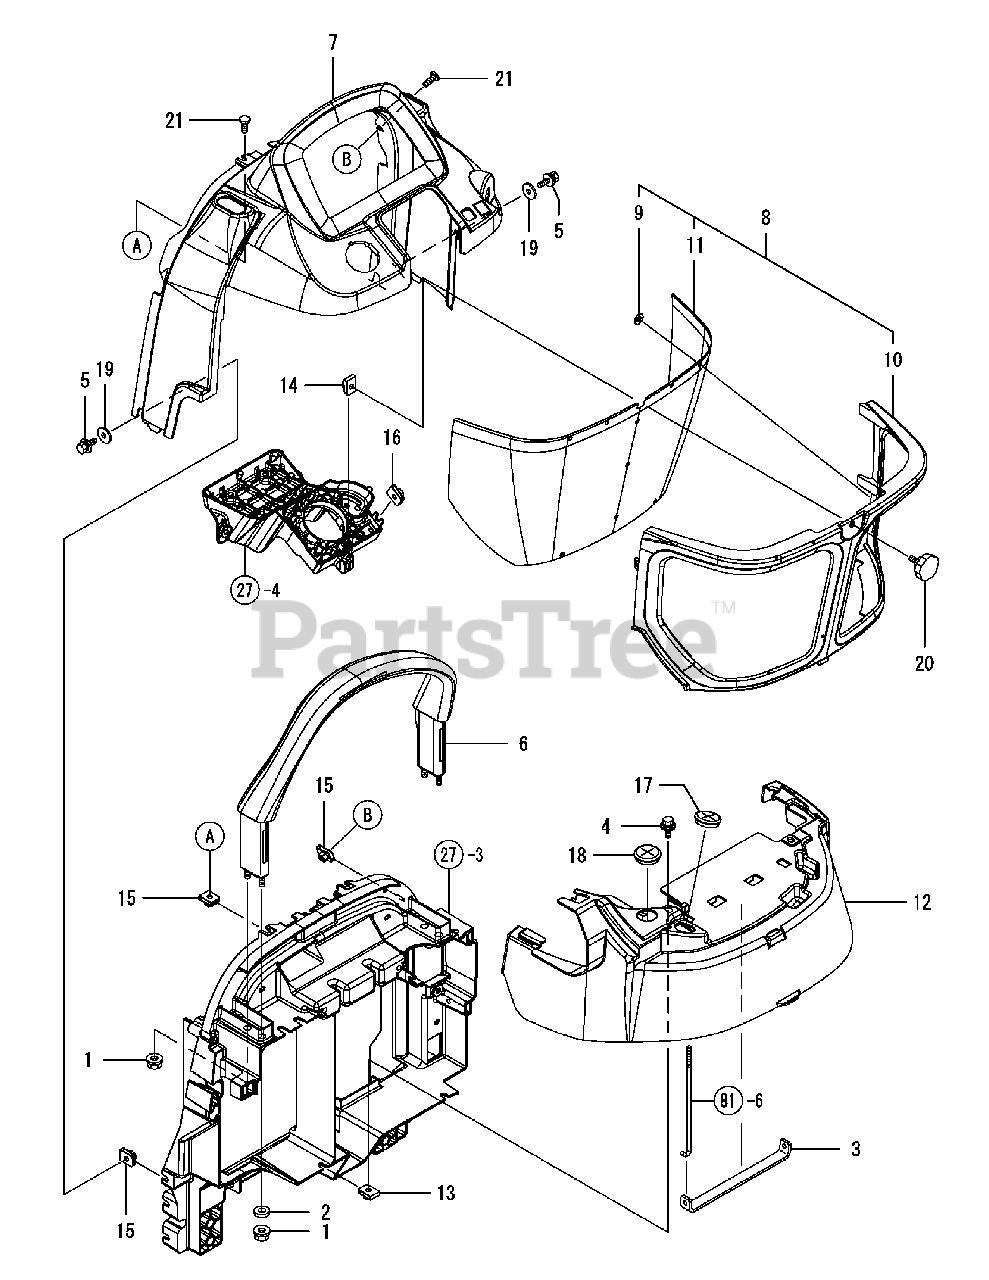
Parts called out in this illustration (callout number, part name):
1	NUT W/WASHER 8
7	COVER, DASHBOARD UPPR
8	DUSHBOARD ASSY, LWR
10	COVER, DUSHBOARD LWR
11	NET, DASHCOVER
12	COVER M ASY DASH BTM
20	BOLT 6X15, WING
21	SCREW M6, BINDING
